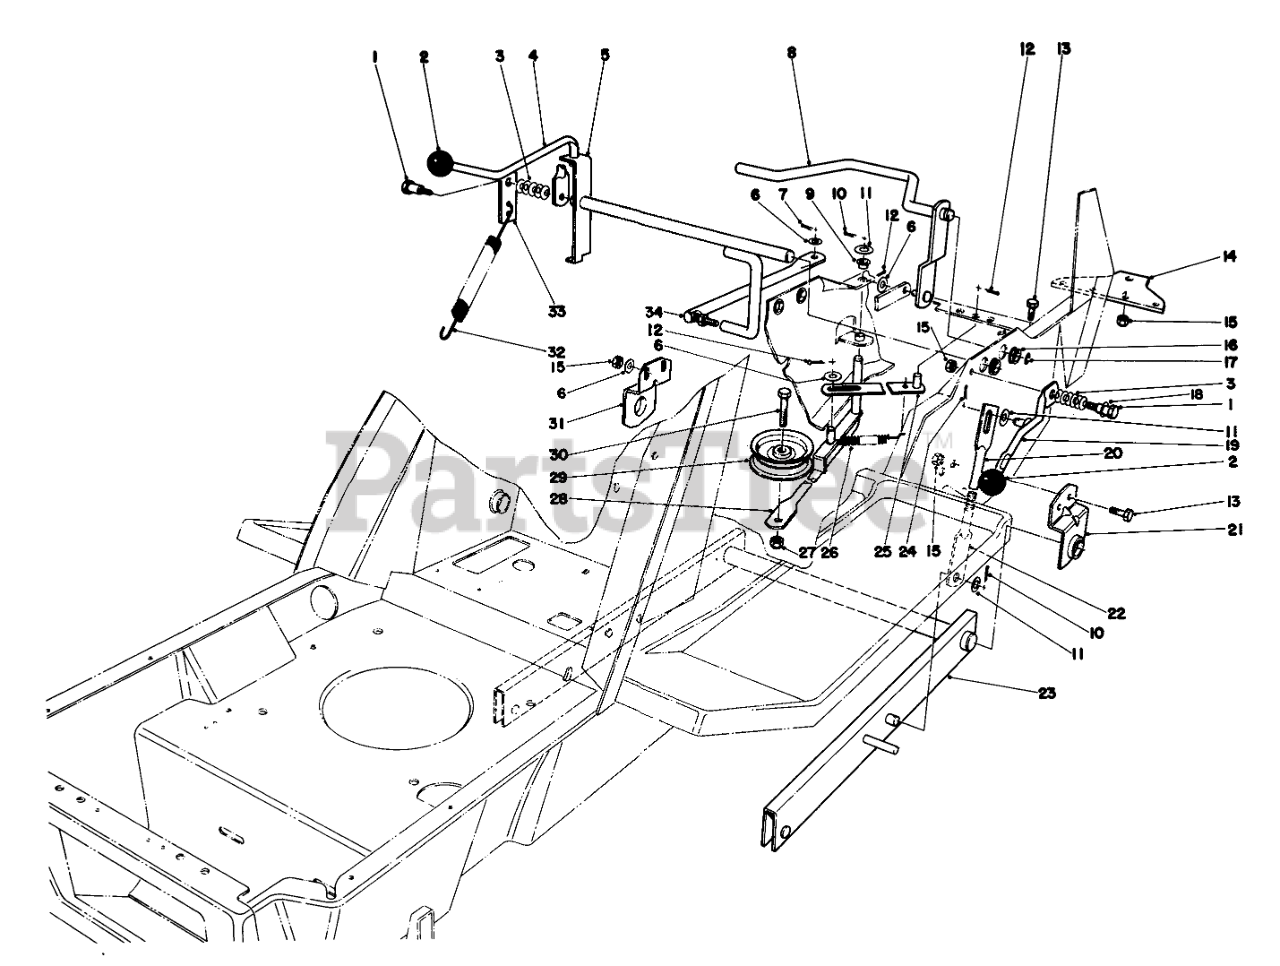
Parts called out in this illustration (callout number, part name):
1	BOLT-SHOULDER
3	WASHER-BELLEVILLE
4	SHIFT LEVER BO
5	Shim Lever
6	WASHER-PLAIN
7	PIN-COTTER
8	CLUTCH ACTUATOR WA B
9	BUSHING-NYLINER
10	PIN-COTTER
11	WASHER-FLAT
12	PIN-COTTER
13	SCREW-HH
14	HITCH PLATE R
15	NUT-LOCK, CONE
16	Nyliner
17	E-RING
18	WASHER-FLAT
19	HOC HANDLE WA B
20	Height of Cut Adjustment Tube
21	LH PIVOT BAR RET B
22	Strap Height of Cut
23	Bar-Pivot
24	PIN-COTTER
25	SPRING RET WA B
26	DECK TENSION SPRNG O
27	NUT-LOCK, CONE
28	IDLER ARM WA BO
29	IDLER PULLEY
30	SCREW-HH
31	RH PIVOT BAR RET B
32	TRACTION SPRING
33	BRKT-COBALANCE SPRING
34	SHIFT ARM BO
